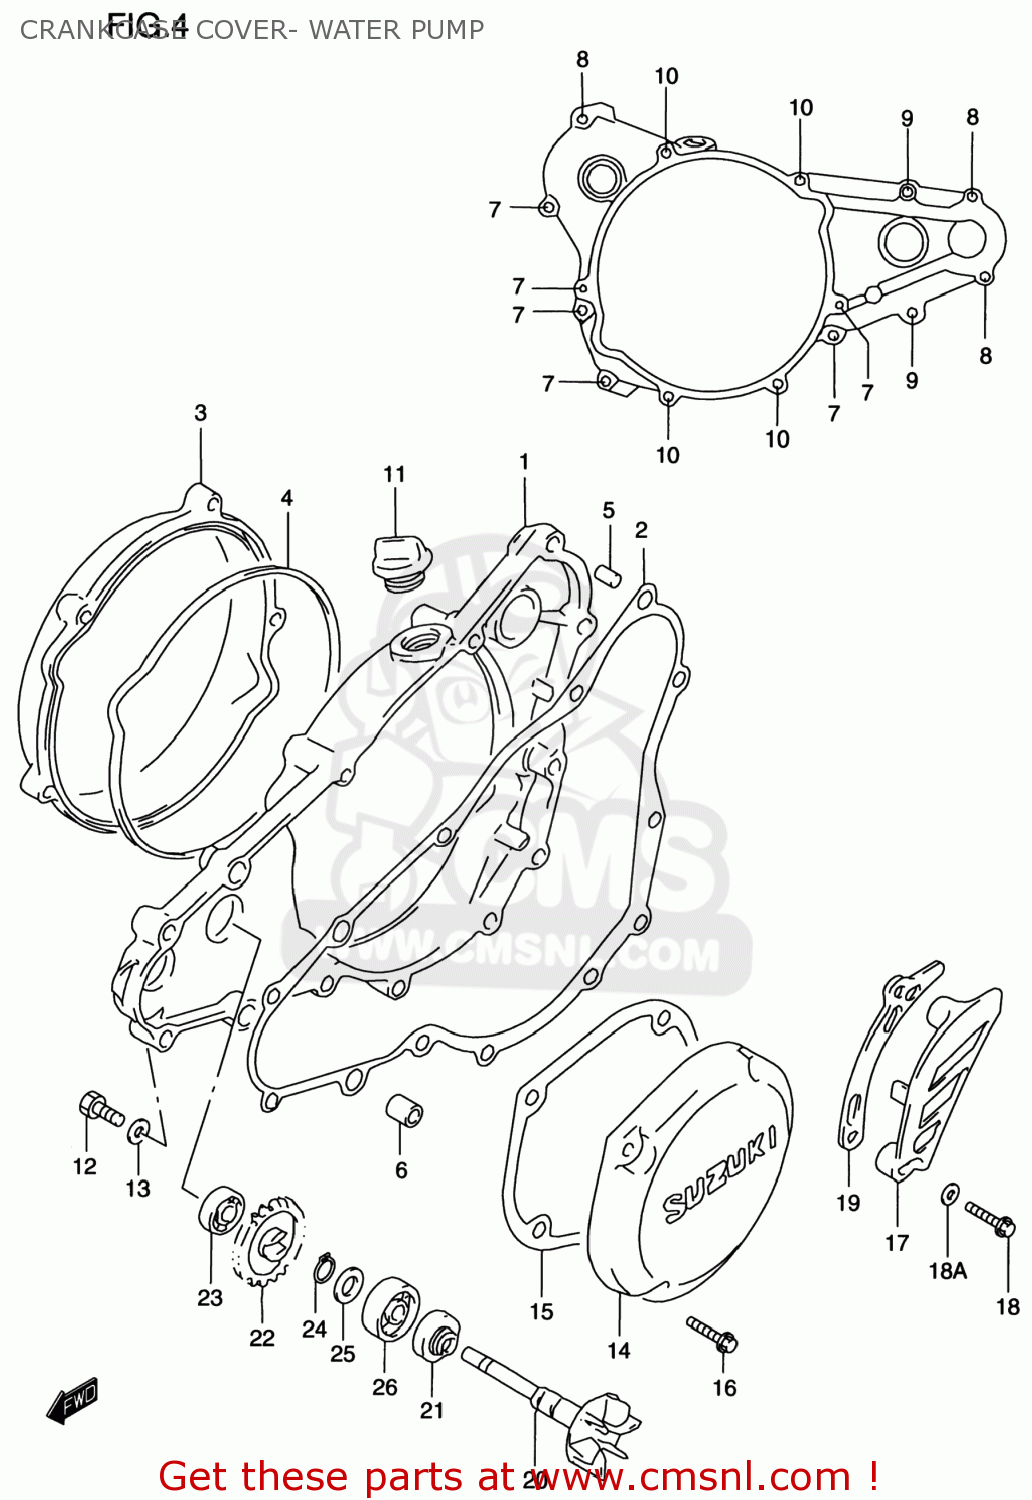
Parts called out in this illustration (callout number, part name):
1	COVER,CLUTCH
2	GASKET,CLUTCH COVER
3	COVER,CLUTCH,OUTER
4	O RING,CL COVER OUTER
5	PIN
6	PIN
7	SCREW
8	BOLT,G/S SWITC
9	BOLT
10	BOLT
11	PLUG SET
12	SCREW(6X10)
13	GASKET(6.2X11X1).2 (NAS)
14	COVER,MAGNETO
15	GASKET,MAGNETO COVER
16	SCREW
17	COVER,ENGINE SPROCKET
18	SCREW
18A	WASHER(6.5X14X2)
19	PLATE,FR CHAIN GUIDE
20	IMPELLER,WATER PUMP
21	SEAL,WATER PUMP OIL
22	GEAR,WATER PUMP DRIVEN
23	BEARING(8X22X7)
24	CIRCLIP,10MM
25	WASHER,THRUST
26	BEARING(10X26X8)
